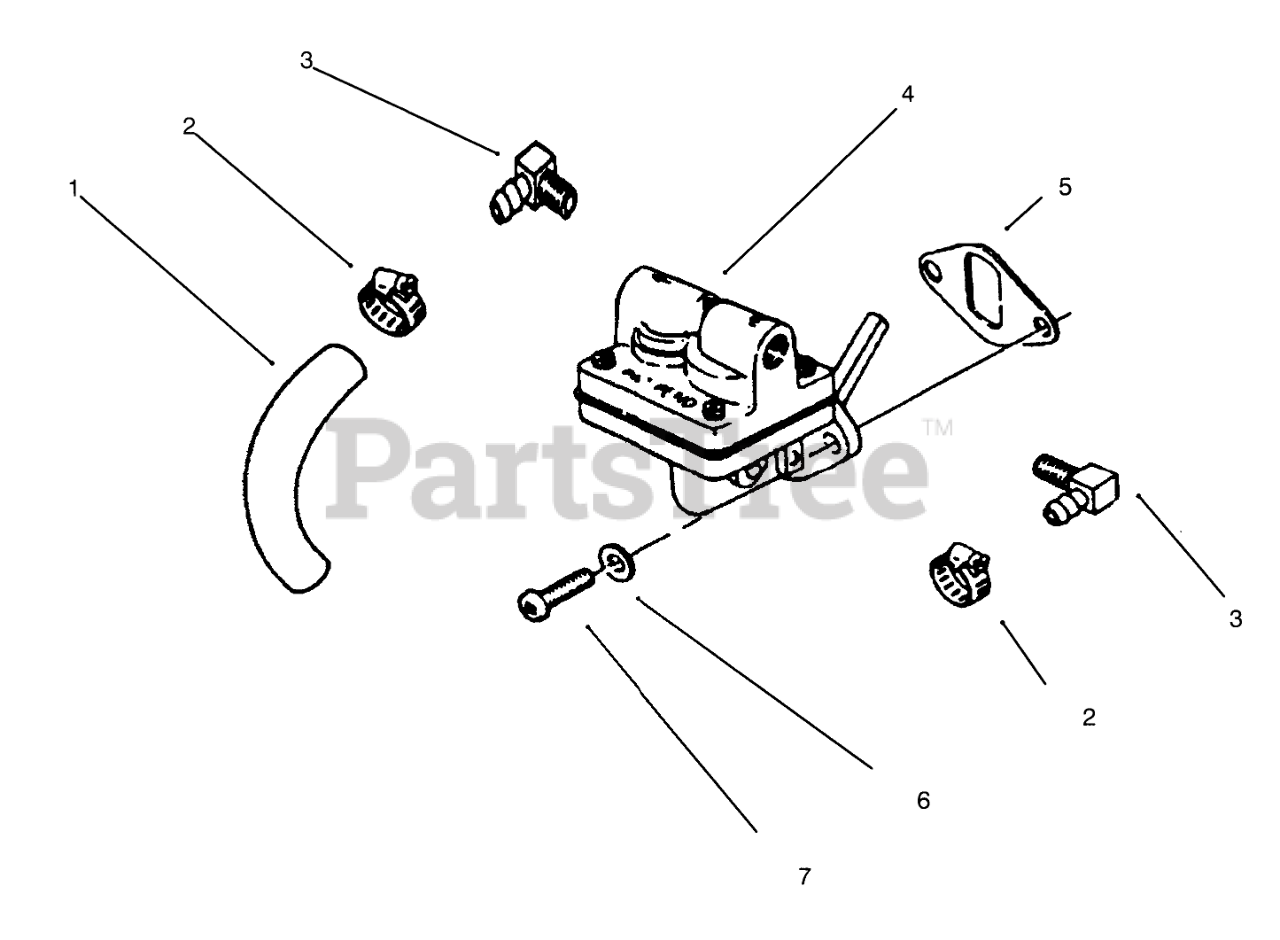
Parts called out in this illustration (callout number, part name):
1	Line-Fuel
2	Clamp
3	Connector 90
4	Pump Assy-Fuel(Incl. Ref.#5 &7)
5	Gasket
6	Washer
7	Screw-Pozidrive
